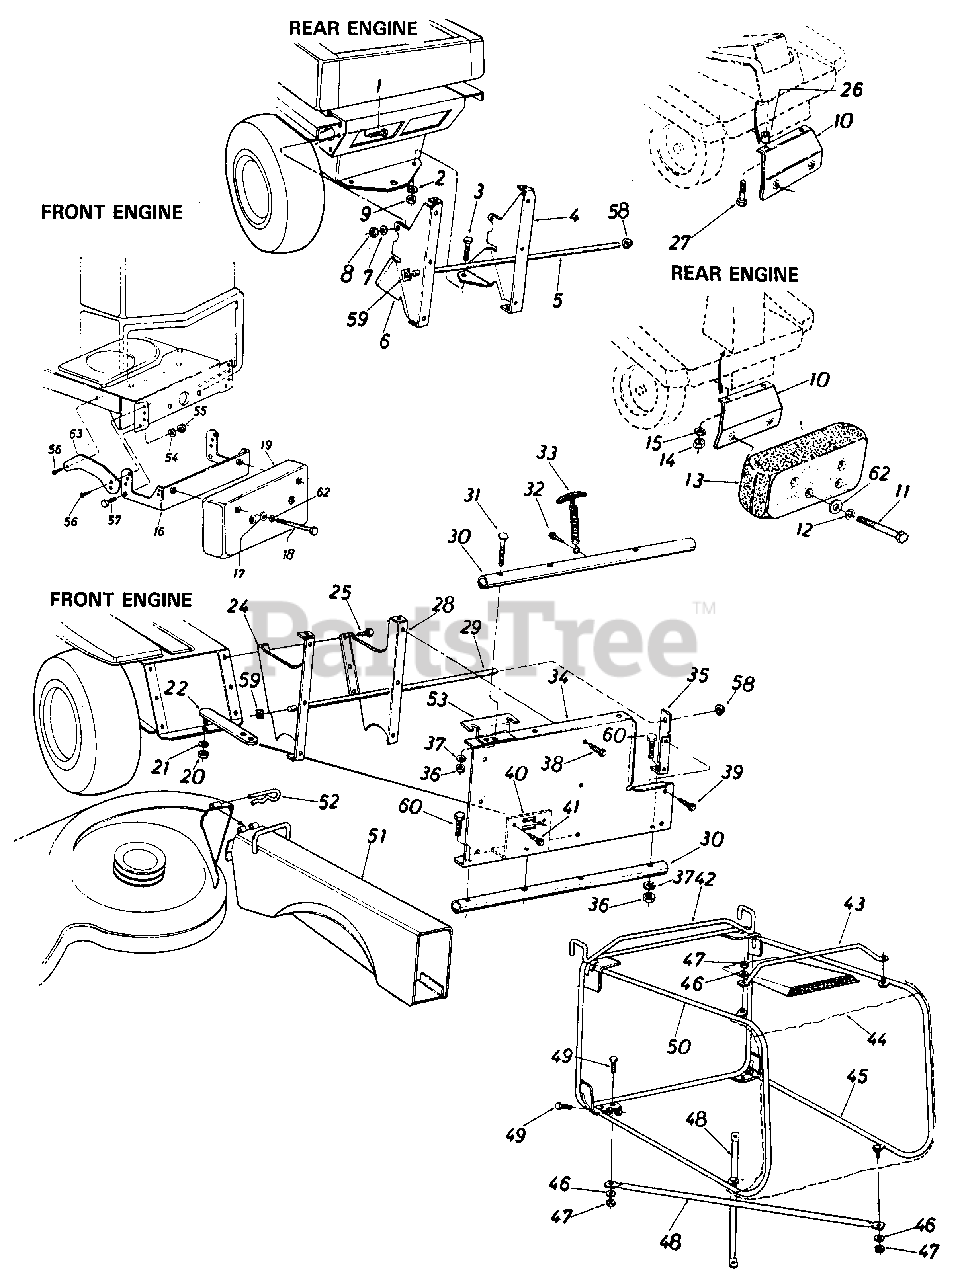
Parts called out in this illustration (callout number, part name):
1	Hex Bolt 5/16-18 x 1-00" Lg. *
2	L.-Wash. 5/16" I.D.*
3	Hex Bolt 5/16-18 x 1.00" Lg. *
4	Catcher Support Brkt R.H.
7	L Wash. 5/16 I.D.
8	Hex Nut 5/16 18 Thd.
9	Hex Nut 5/16 18 Thd.*
10	Counterweight Bracket
11	Hex Bolt 3/8-16 x 4.5" Lg.*
12	Belleville Wash. .400" I.D. x.88" O.D.
13	Front Counterweight 381 bs.
14	Hex Nut 5/16-18 Thd.*
15	L. Wash. 5/16" I. D. *
16	Counterweight Bracket
17	Belleville Wash. .400" I.D. x.88" O.D.
18	Hex Bolt 3/8-16 x 4.5" Lg.
19	Front Counterweight 38 Ibs.
20	Hex Jam Nut 1/2-13 Thd.*
21	L. Wash. 1/2" I.D.*
25	Hex Wash. Hd. Self Tap Scr. 5/16-18 x .75 Lg.*
26	Spacer.380" I.D. x 1.00" O.D. x.320" Lg.
27	Not Part of Kit
28	Catcher Support Brk't.R. H.
31	Curved Carriage Bolt 5/16-18 x 1.75 Lg.
32	Hex "AB"-Tap Scr. 1/4" x .62" Lg.
33	Hood Latch Ass'y.
34	Grass Catcher Adapter
35	Grass Catcher Support Brk't. R.H.
36	Hex Nut 5/16-18Thd.*
37	L.-Wash.5/16" I.D.*
38	Hex Wash. Hd. Self Tap Scr. 1/4-20 x .50" Lg.
39	Hex Wash. Hd. Self Tap Scr. 1/4-20 x .50" Lg.
40	Hitch Bracket
41	Hex Wash. Hd. Self Tap Scr. 1/4-20 x .50" Lg.
42	Grass Bag Frame Ass'y.
43	Grass Catcher Handle 26.75
44	Grass Catcher Bag
47	Hex L.-Nut 1/4-20Thd.
48	Bottom Cross Brace 30.36" Lg. *
49	Hex Bolt 1/4-20 x .62" Lg.
52	Not Part of Kit
53	Grass Catcher Support Plate
54	L.-Wash. 7/16" I.D.*
55	Hex Nut 7/16-20 Thd.*
56	Hex AB Tap Scr.5/16-18 x 9.
57	Hex Bolt 7/16-20x 1.00" Lg. *
59	Speed Nut
60	Hex Bolt 5/16-18 x 1.75" Lg. *
62	Fl.-Wash. .390" I.D. x 1.12" O.D. x .187 Thk.
63	Tie Strap
